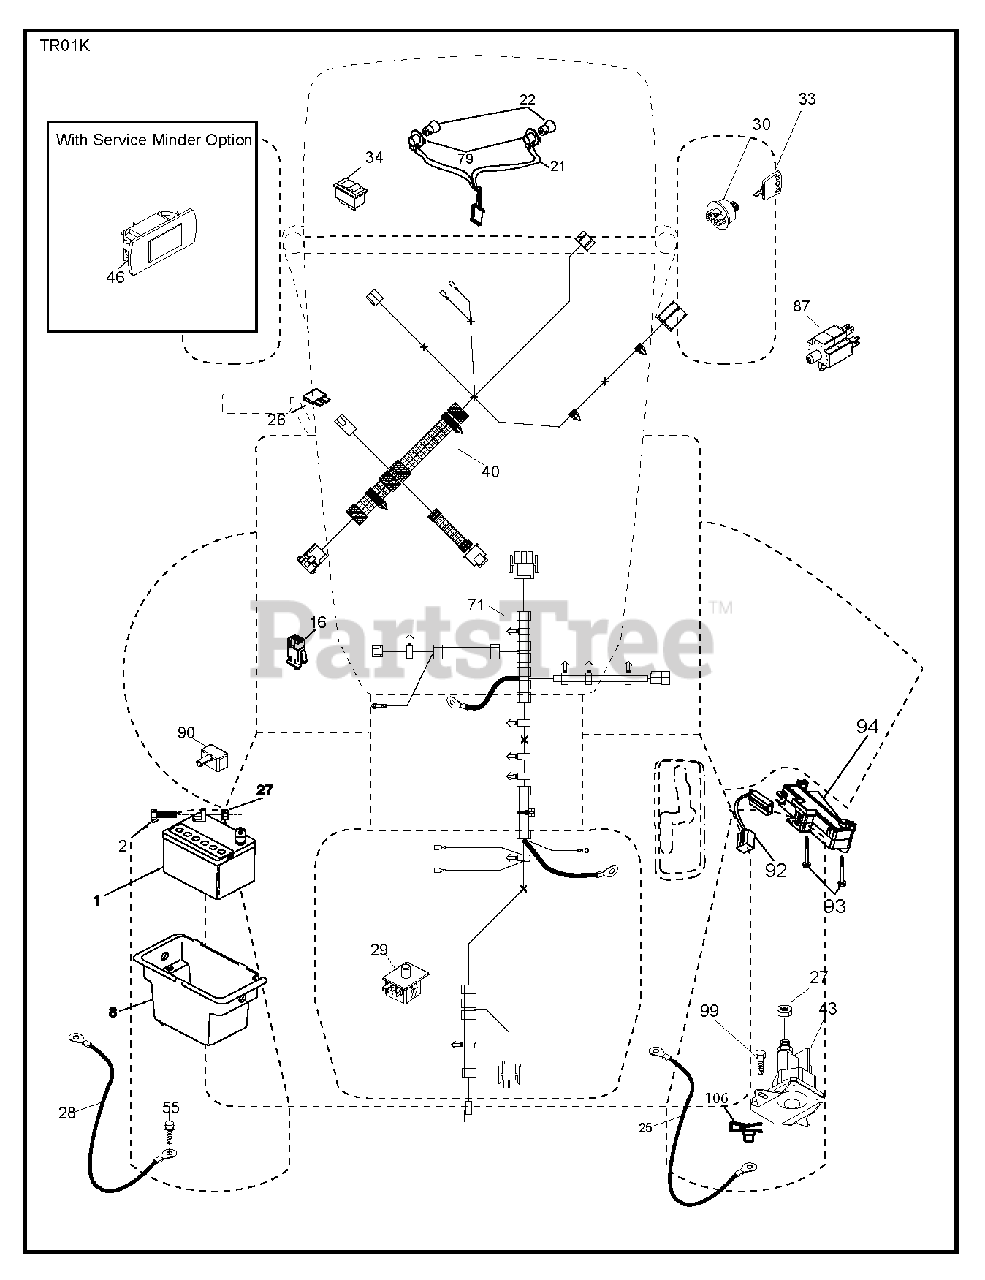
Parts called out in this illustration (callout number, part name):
1	REPL BY 532 12 38-99
2	BOLT.HEX.1/4.X.3/4.DICHROMATE
8	BOX.BATTERY.MNT.REAR.L
16	SWITCH INTERLOOK PUSH-IN
21	HARNESS.W/LIGHT SOCKET
22	LIGHTBULB
25	CABLE.STARTER.6GA.BL/RED.14.
26	FUSE 20AMP
27	NUT
28	CABLE.BLACK.18"REAR.BA
29	SWITCH.SEAT.DP W/RAMPS
30	SWITCH.IGN.DELTA.W.LGH.ROS
33	KEY.CHAIN.BLISTER.PACK.GEN.INT
34	SWITCH LT
40	HARNESS IGN. DASH
43	SOLENOID.W/BRASS.PLUNGER
55	SCREW 5/16"
71	HARNESS.CHASSIS.TEX.8AWG
79	BULB HOLDER ASM.
87	SWITCH.INTRLCK.CLUTCH.
90	COVER.TERMINAL.BATTERY
92	HARNESS.PIGTAIL.CONSLE
93	SCREW.PLASTITE
94	MODULE.REVERSE.ROS
99	SCREW HEXWSHR 1/4-20X3/4
106	1/4-20 U NUT
